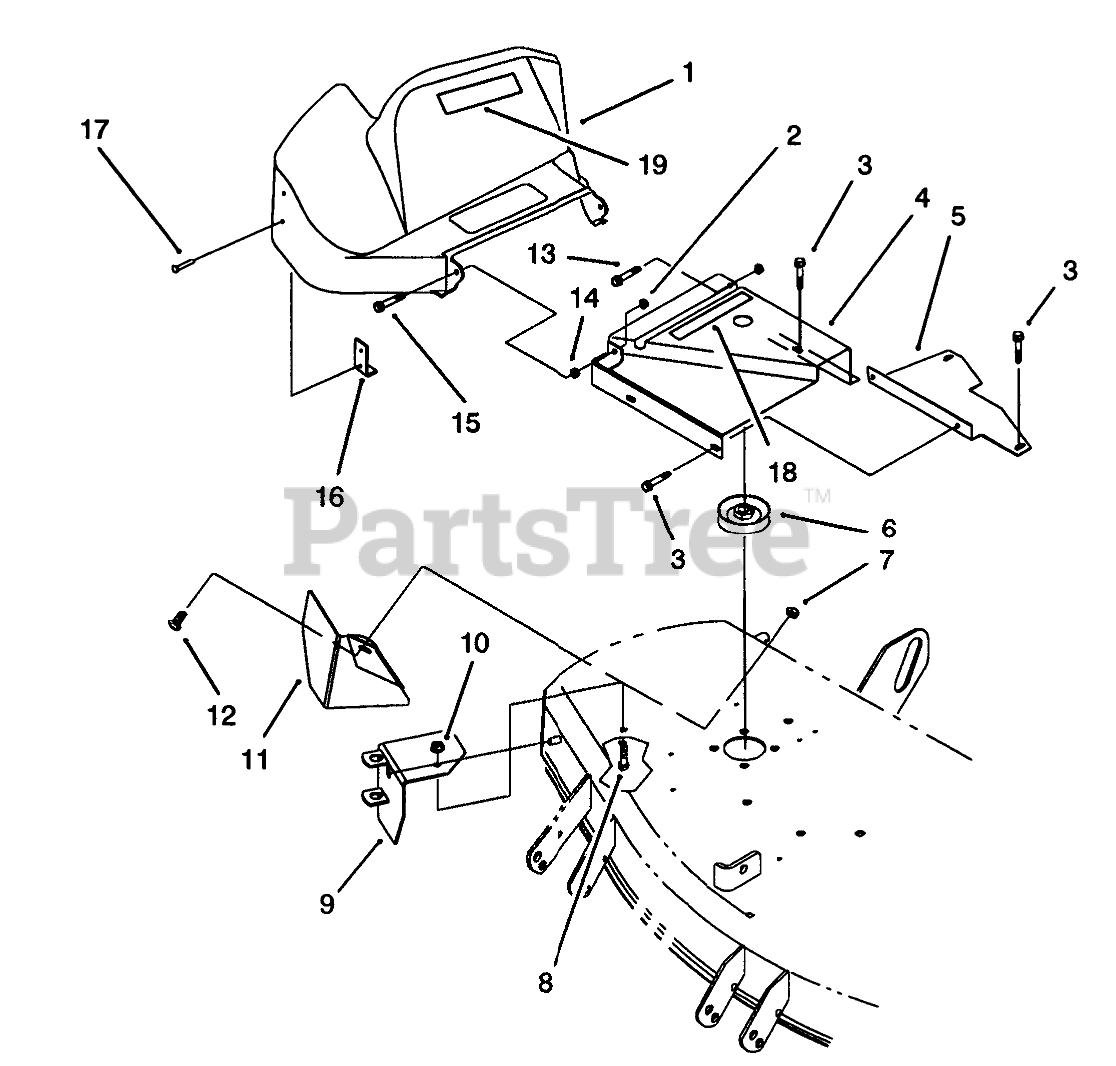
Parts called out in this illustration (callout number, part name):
1	SHIELD-BELT
2	NUT-LOCK, NI
3	Bolt
4	Inner Shield Assembly (Incl. Ref. #18)
5	42" ADAPTOR SHIELD B
6	42" Y PULLEY
7	NUT-LOCK, NI
8	SCREW-HH
9	PIVOT SUPPORT ASM
10	NUT-HF
11	42" DEFLECTOR B
12	SCREW-CARR
13	SCREW-HH
14	NUT-HEX
15	SCREW-HH
16	BRACKET-SUPPORT, SHIELD
17	RIVET-POP
18	DECAL - DANGER
19	DECAL - DANGER
